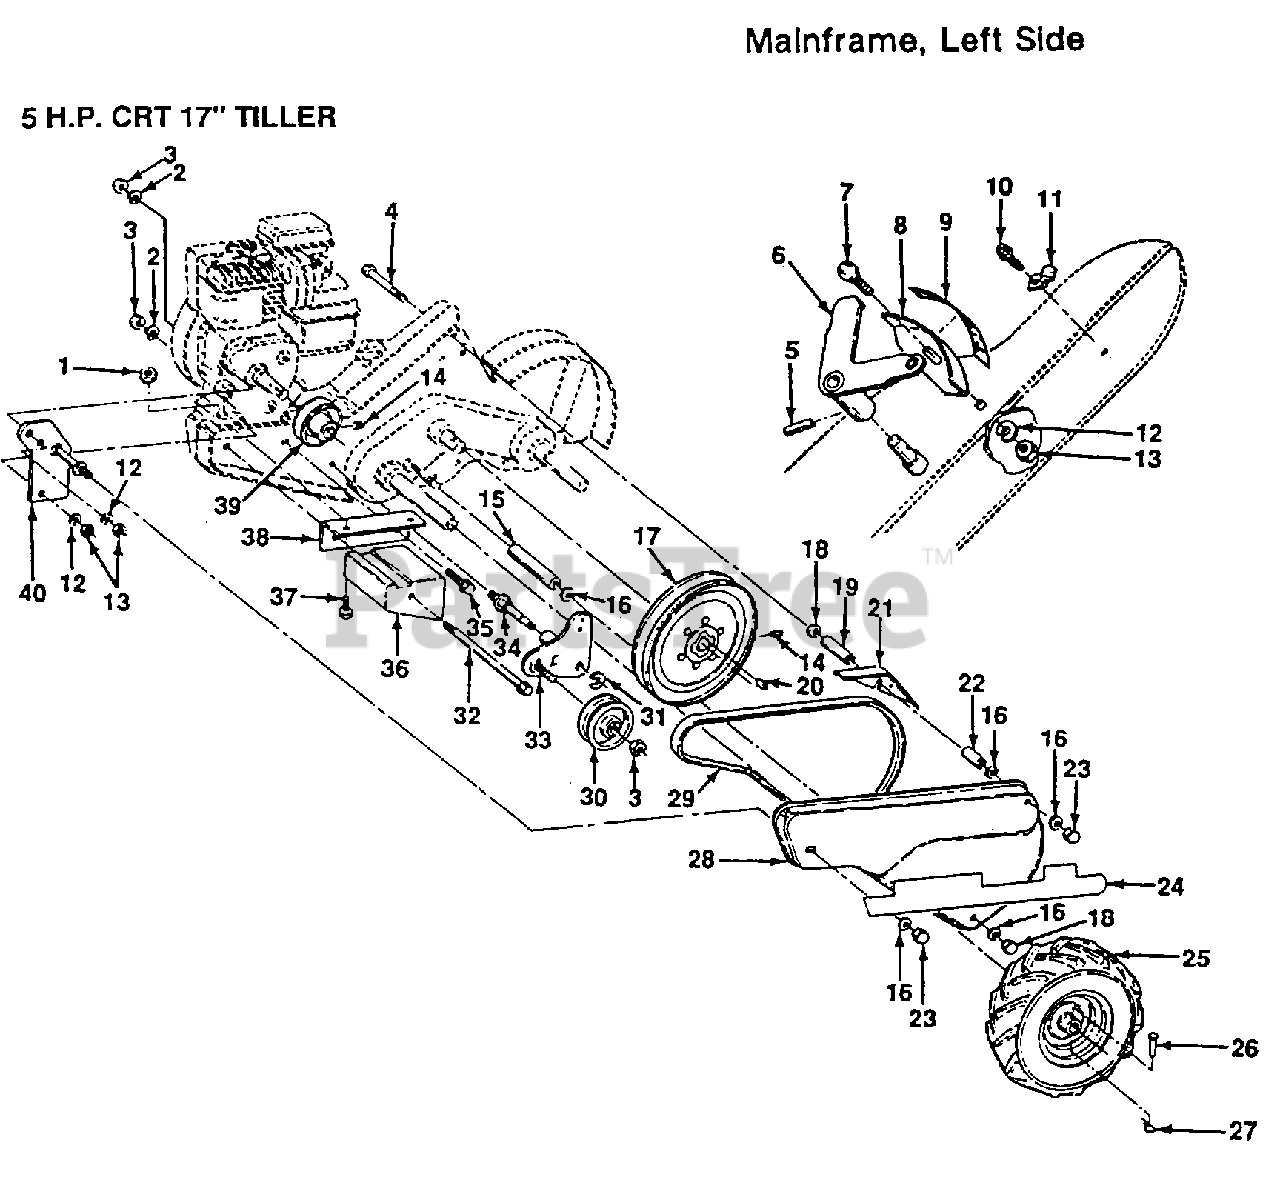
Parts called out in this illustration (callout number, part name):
2	LOCKWASHER
3	NUT.HEX.3/8-16UNC
4	BOLT-HEX TI
6	LEVER ASM CRT
7	BOLT
8	PANEL TI
11	CONDIUT CLIP T
12	LOCKWASHER
14	SET SCREW
15	SPACER
16	WASHER
17	"SHEAVE 10"" CRT"
18	NUT.HEX.5/16-18
19	SPACER CRT
20	KEY T
21	GUARD CRT
22	SPACER CRT
23	NUT TI
25	TIRE.CHV.13X5.0-6
27	RETAINER M
30	PULLEY-IDLER TI
31	KLIP RING
32	BOLT CRT
34	SHIFT ARM CRT
35	BOLT
36	COUNTERWEIGHT CRT
37	BOLT.HEX.5/16-1.5
38	BRACKET LH CRT
40	BRACKET ASSY CRT
